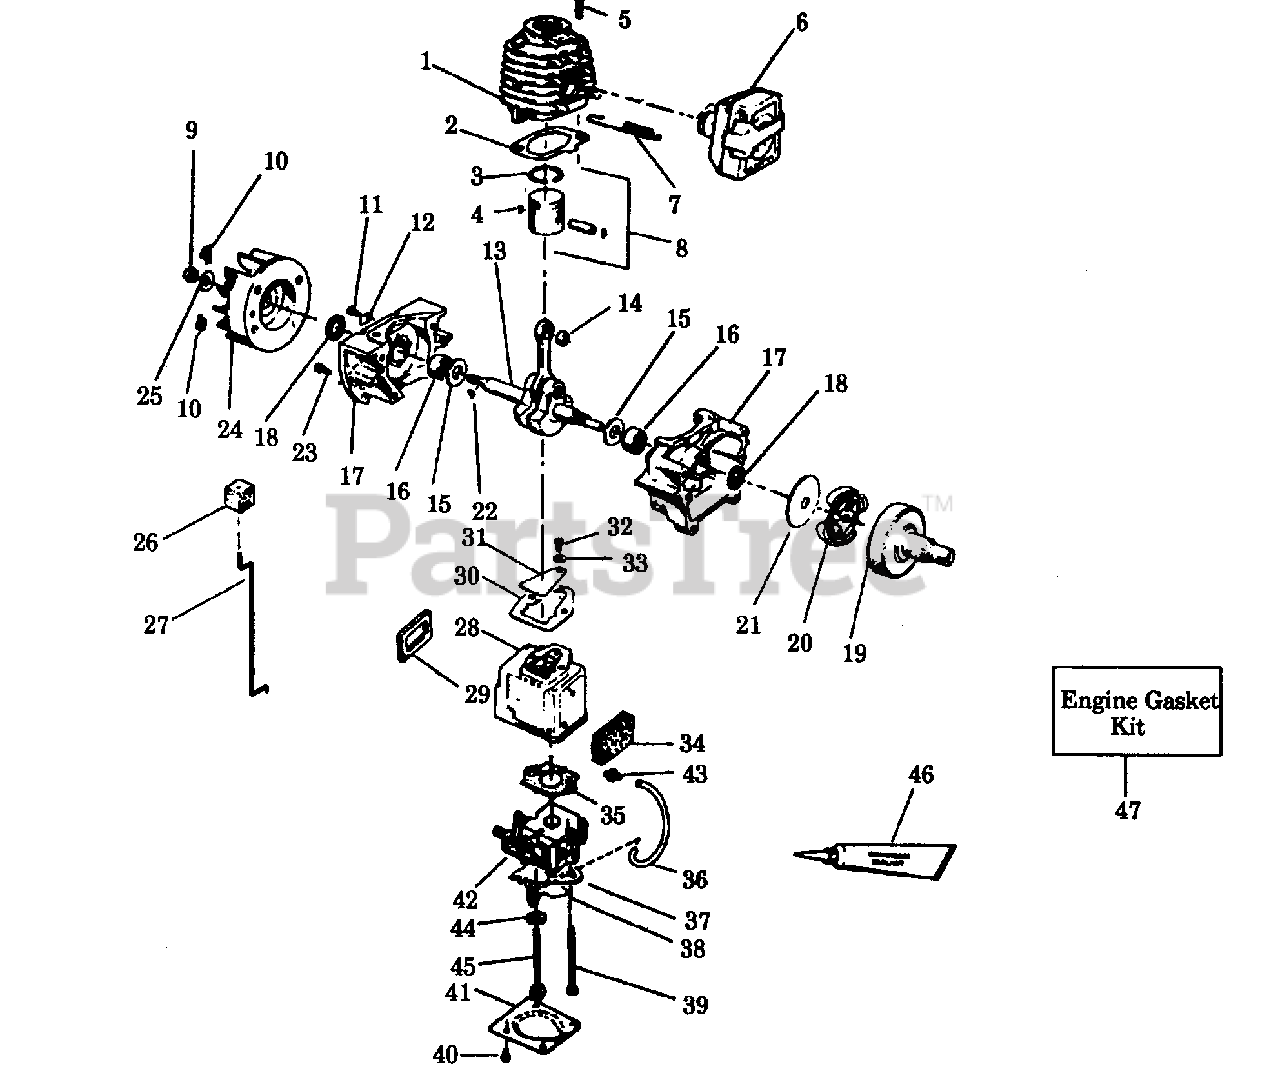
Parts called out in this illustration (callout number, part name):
1	T1
2	Cylinder Gasket
4	Wrist Pin Retainer
6	Muffler Ass'y.
7	Muffler Attach. Spring
10	Starter Dog Spring
12	Choke Wire Clamp
14	Wrist Pin Bearing
17	Crankcase Ass'y. (Inc.16,18 & 23)
18	Crankcase Seal
19	Drum & Coupling Ass'y.
20	Clutch Ass'y. Kit
21	Clutch Washer Kit
22	Flywheel Key
24	Flywheel Ass'y.
26	Choke Wire Boot
27	Choke Wire
28	Carb. Hsg.
29	Seal
30	Gasket
31	Reed Valve
34	Seal
35	Gasket
36	Fuel Line
37	Guide Plate
38	Choke Shutter
41	Carb. Case Cover
42	Carburetor-WA-149
43	Fuel Line Fitting
46	Crankcase Sealant
47	Engine Gasket Kit
